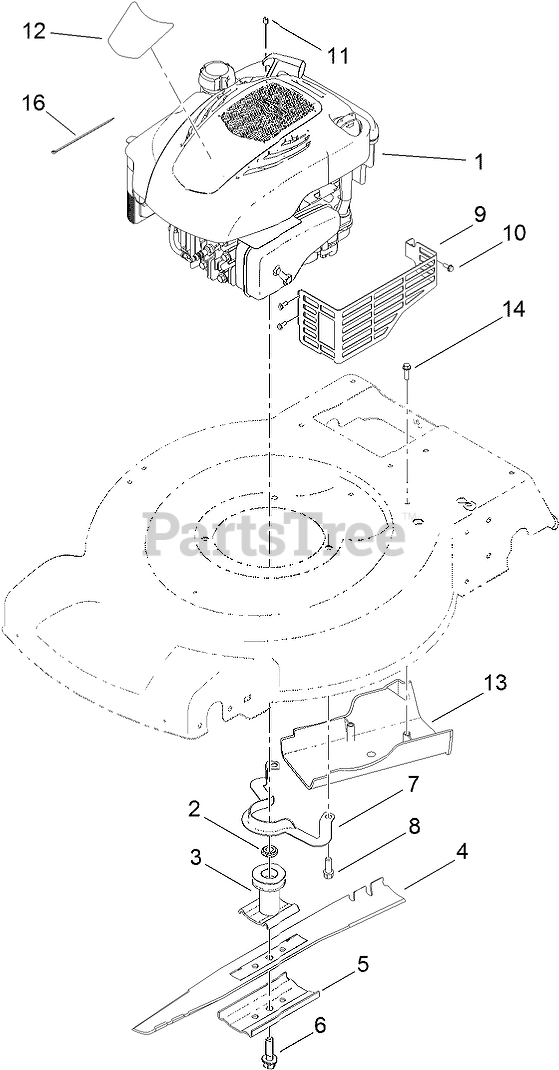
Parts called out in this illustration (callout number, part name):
2	Spacer-Driver
3	DRIVER-BLADE
4	BLADE
5	Accelerator-Blade
6	BOLT-BLADE
7	Guide-Belt
8	SCREW-TAPTITE
9	SHIELD-MUFFLER
10	SCREW-TAPTITE
11	STOP-ROPE
12	DECAL-SHROUD
13	COVER-BELT
14	SCREW-HWH
16	TIE-CABLE, MOTOR
